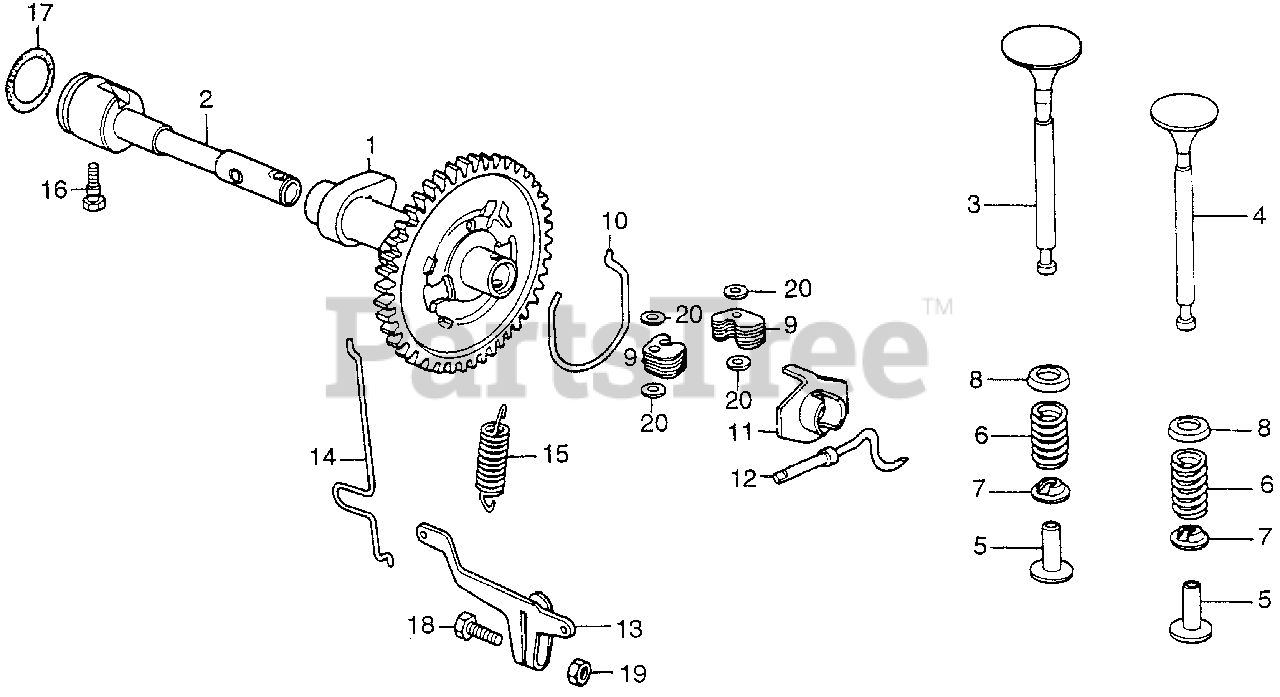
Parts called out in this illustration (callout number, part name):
2	CENTER, CAMSHAFT
3	VALVE, IN. (NOT AVAILABLE)
4	VALVE, EX.
5	LIFTER, VALVE
6	SPRING, VALVE
7	RETAINER, VALVE SPRING
8	SEAT, SPRING (NOT AVAILABLE)
9	WEIGHT, GOVERNOR
10	CENTER, GOVERNOR WEIGHT
11	SLIDER, GOVERNOR
12	SHAFT, GOVERNOR ARM
13	ARM, GOVERNOR (NOT AVAILABLE)
14	ROD, GOVERNOR (NOT AVAILABLE)
15	SPRING, GOVERNOR (NOT AVAILABLE)
16	BOLT, CAMSHAFT CENTER STOPPER
17	O-RING (23.5X2.1) (ARAI)
18	BOLT, HEX. (6X16)
19	NUT, HEX. (6MM)
20	WASHER, PLAIN (3MM)
